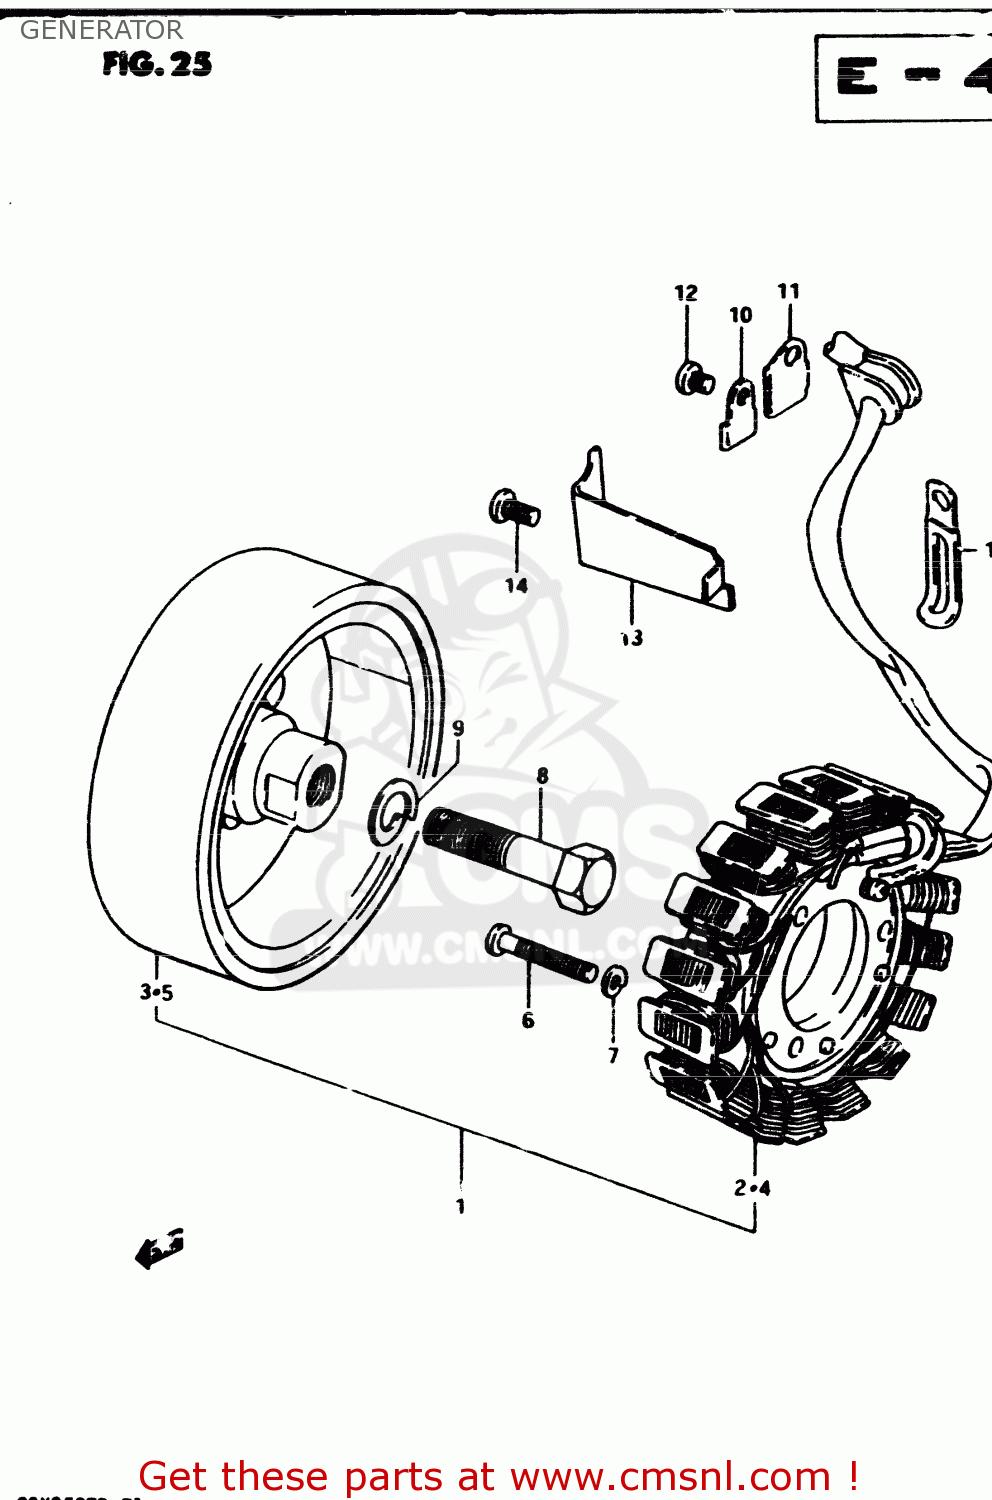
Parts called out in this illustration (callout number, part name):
1	GENERATOR ASSEMBLY
2	STATOR ASSEMBLY
3	ROTOR ASSEMBLY
4	STARTER ASSY
5	ROTOR ASSEMBLY
6	SCREW
7	LOCK WASHER
8	BOLT 12X45
9	WASHER,LOCK 12
10	CLAMP,GENERATOR LEAD WIRE
11	CLAMP,GENERATOR LEAD WIRE
12	SCREW
13	CLAMP,GENERATOR LEAD WIRE
14	SCREW
15	CLAMP L:35
